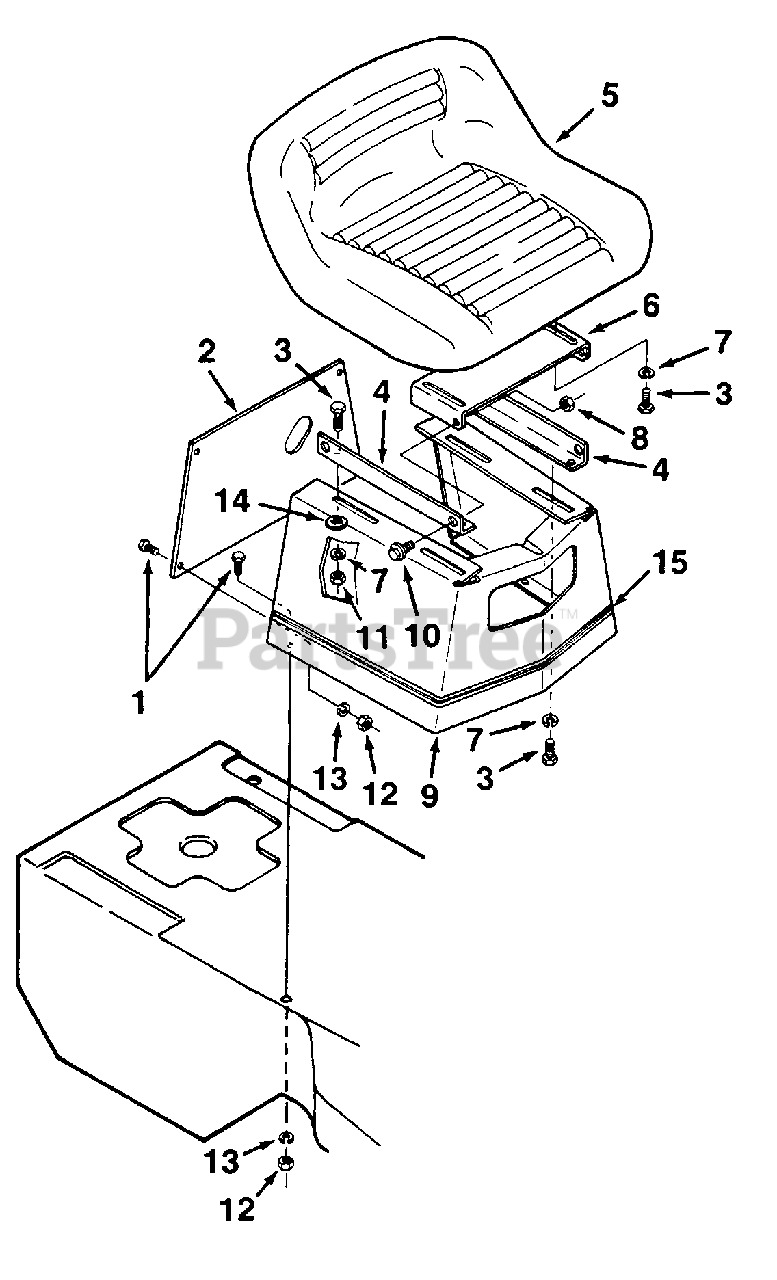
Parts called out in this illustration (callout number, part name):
3	SCREW- 5/16-18 x 3/4 hex
7	WASHER
9	SUPPORT- Seat
11	NUT
12	NUT
14	WASHER
